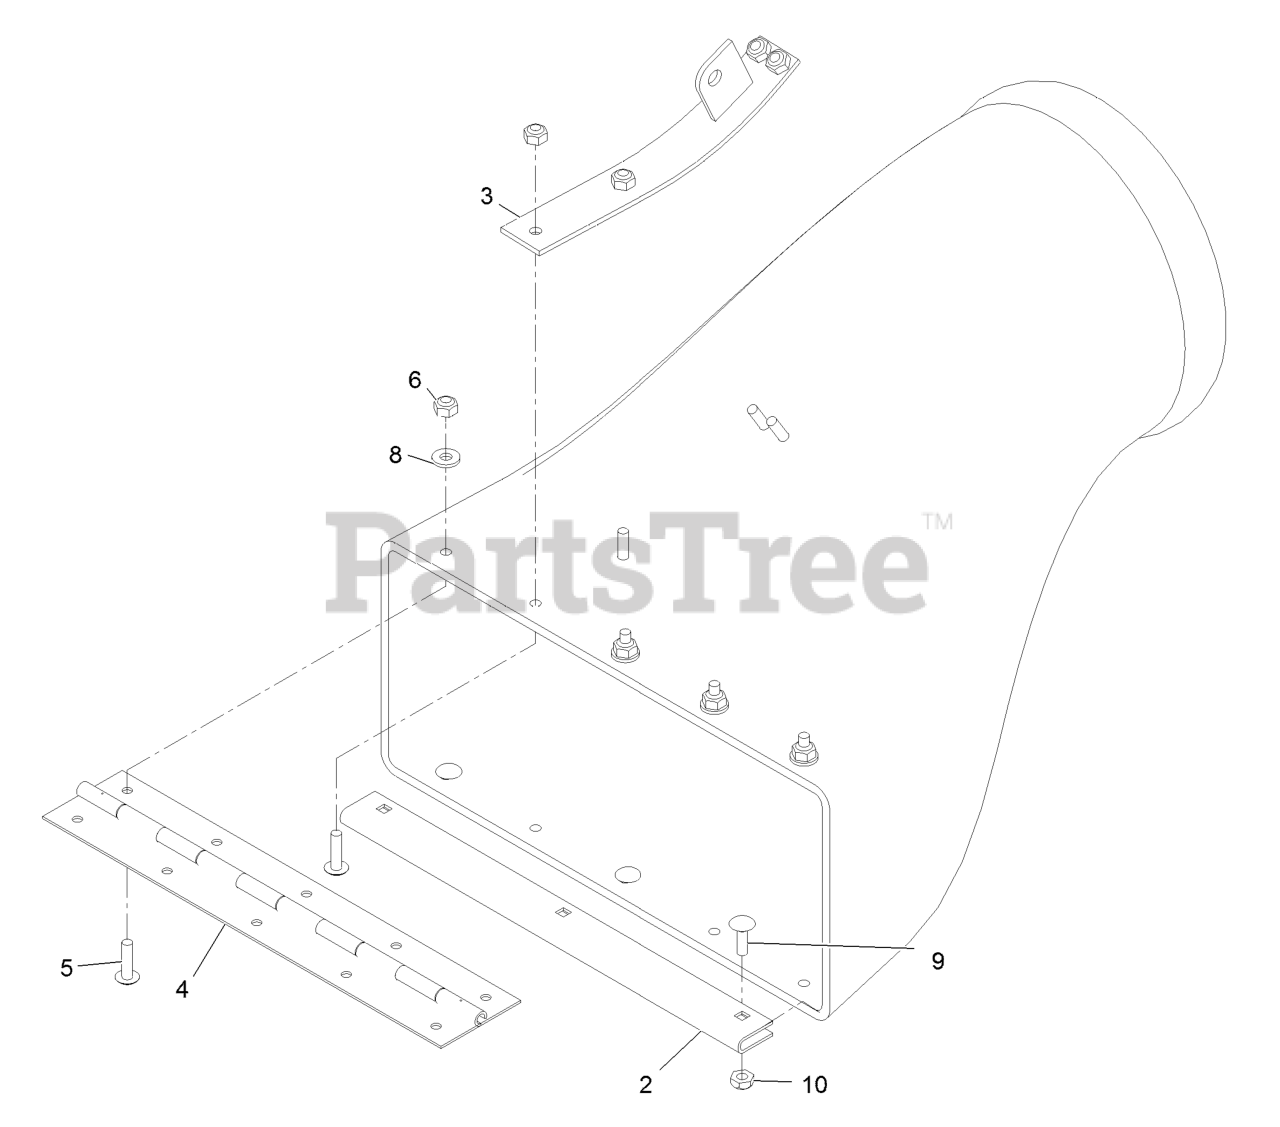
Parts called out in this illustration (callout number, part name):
2	GUARD-PLENUM
3	MOUNT-SPRING
4	HINGE-PIANO
5	SCREW-HEAD, TRUSS
6	NUT-LOCK, NI
8	WASHER-FLAT
9	BOLT-CARR
10	NUT-LOCK, NI
